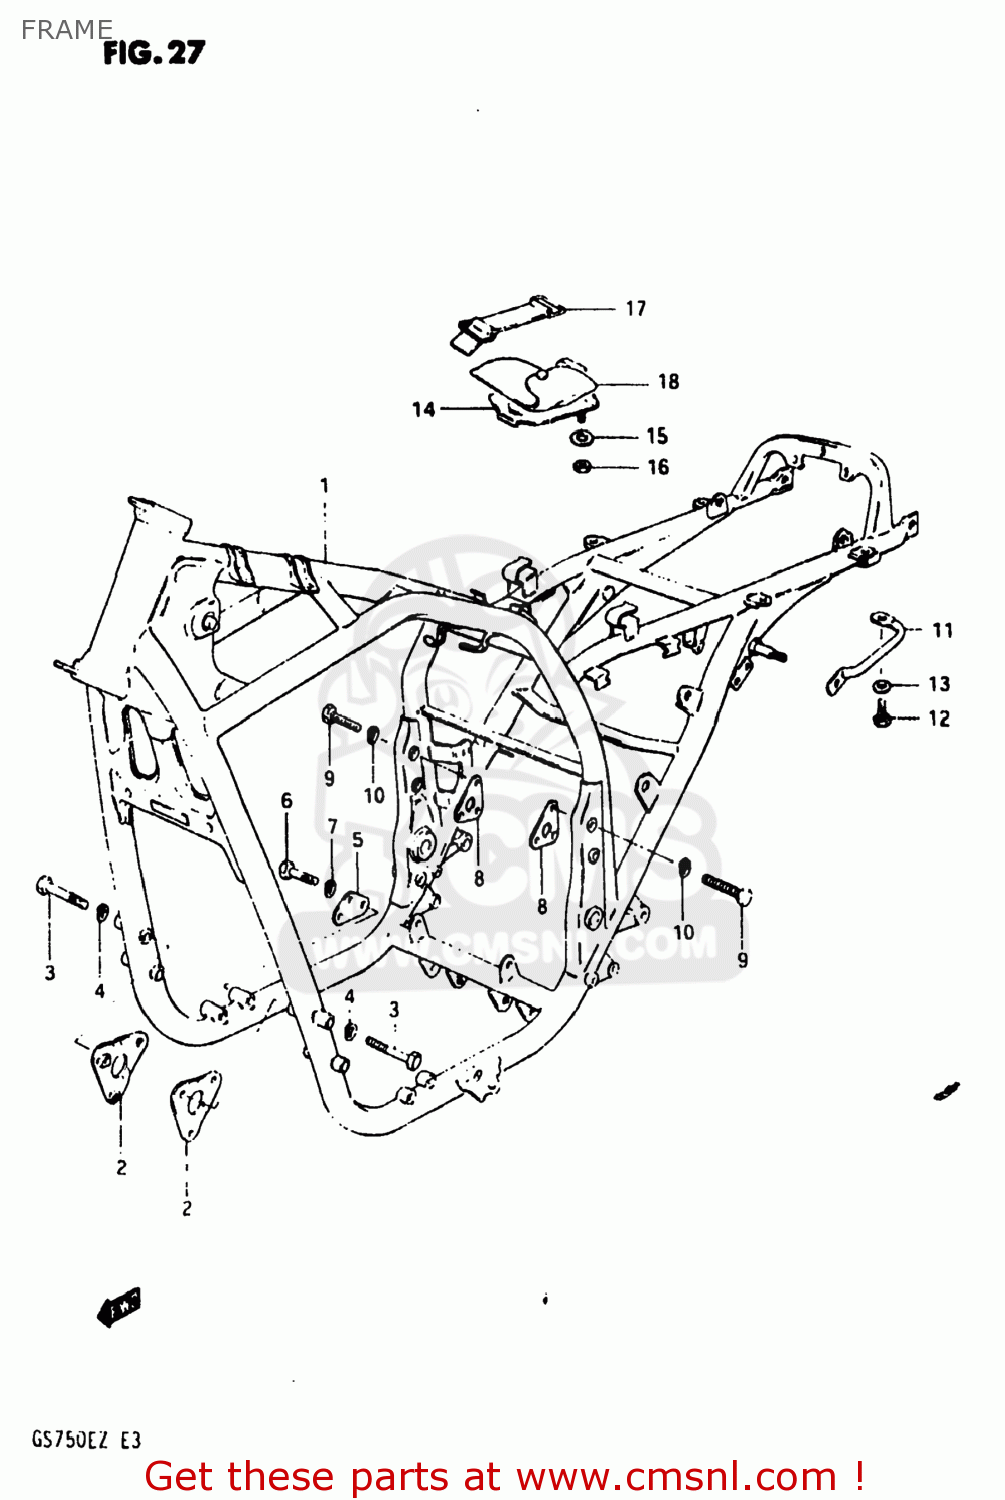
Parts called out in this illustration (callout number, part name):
1	FRAME
2	PLATE,ENG MTG NO.1
3	BOLT
4	LOCK WASHER
5	PLATE,ENGINE MOUNTING
6	BOLT
7	LOCK WASHER
8	PLATE,ENGINE MOUNTING
9	BOLT
10	LOCK WASHER
11	GRIP,FRAME
12	BOLT
13	WASHER
14	HOLDER,TOOL
15	WASHER
16	NUT
17	BAND
18	TOOL SET
